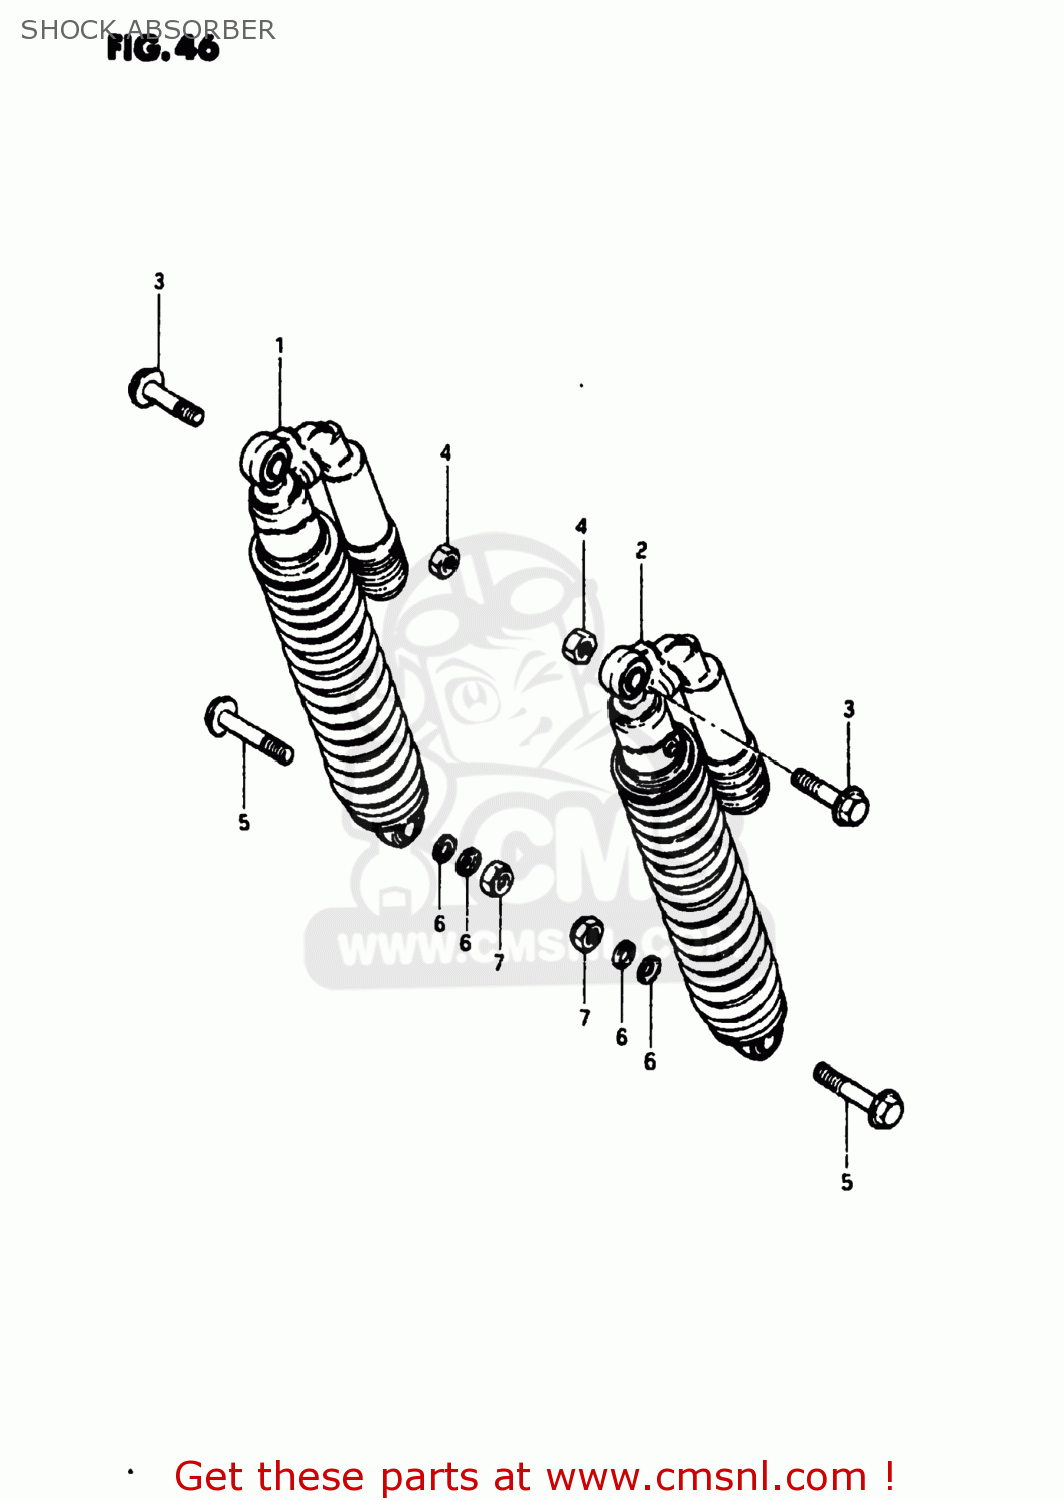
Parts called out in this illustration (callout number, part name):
1	ABSORBER ASSEMBLY,REAR SHOCK
2	ABSORBER ASSEMBLY,REAR SHOCK
3	BOLT(10X40)
4	NUT
5	BOLT
6	WASHER,REAR SHOCK ABSORBER
7	NUT
